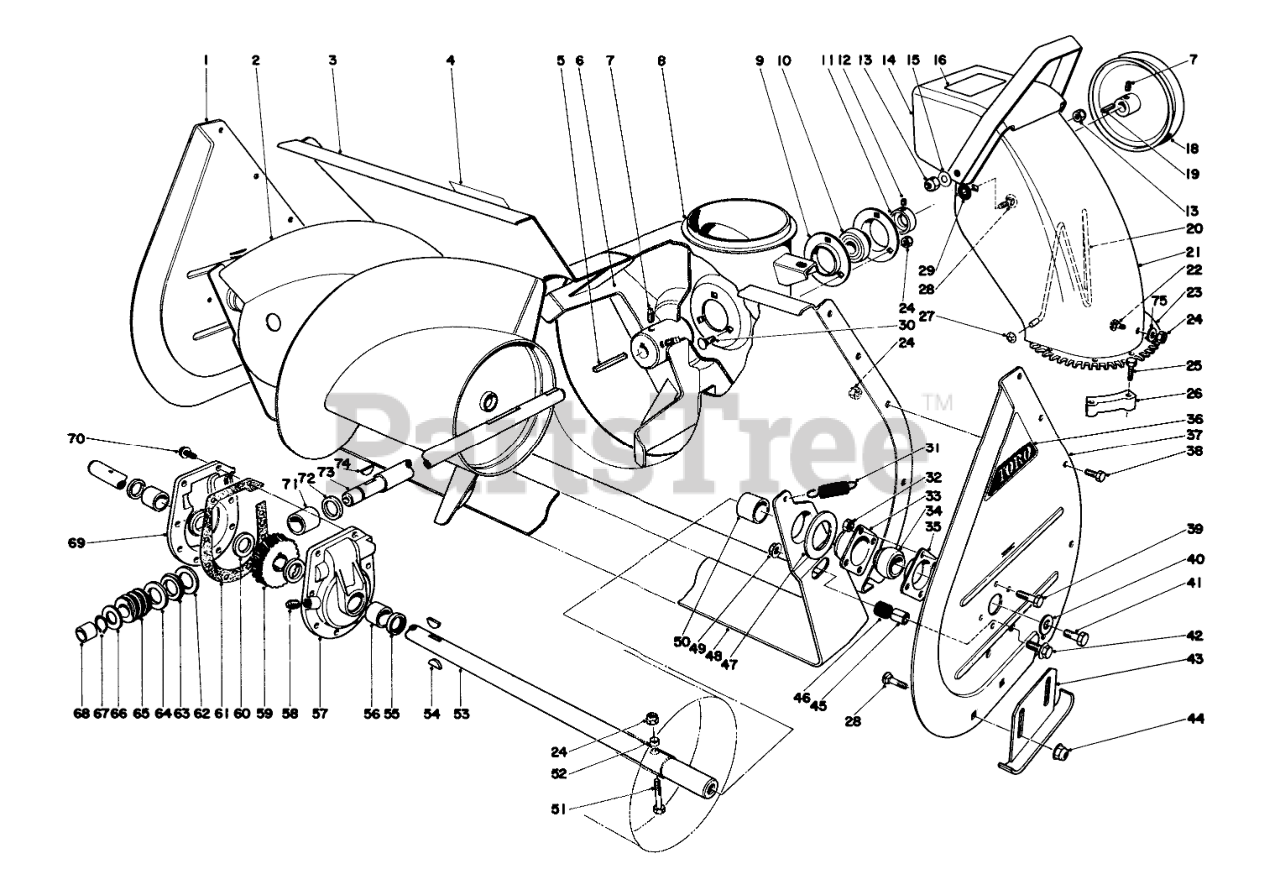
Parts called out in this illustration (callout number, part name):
1	Side Plate
2	Auger R.H.
3	AUGER HSG WA 26" R
4	Decal
6	IMPELLER ASM
7	SCREW-SET, SQH
8	CHUTE RING
9	BRG FLANGE
10	BALL BRG W/COLLAR
11	EXT LOCKING COLLAR
12	SCREW-HSH
13	NUT-LOCK, CONE
14	Deflector (Incl. Ref. #16)
15	WASHER-BELLEVILLE
16	CHUTE WARNING DECAL
18	1/2 X 9.5 DIA PULLEY
19	SQUARE KEY
20	WIRE-CHUTE
21	Upper Chute
22	SCREW-CARR
23	Screw
24	NUT-LOCK, CONE
25	SCREW-TAP
26	RETAINER-CHUTE
27	NUT-PUSH
28	SCREW-CARR
29	WASHER-RUBBER
30	BOLT-CARR
31	SPRING-TENSION
33	BEARING-FLANGE, FRONT
34	BEARING
35	BEARING-FLANGE, REAR
36	AUGER SIDE PLT DECAL
37	Side Plate L. H.
38	SCREW-HH
39	SCREW-HH
40	WASHER
41	SCREW-HH
42	SCREW-HHF
43	Skid
44	NUT-HHF, WHIZ
45	SCRAPER STOP SPACER
46	SCRAPER STOP CUSHION
47	SCRAPER BLADE SPACER
48	SCRAPER BLADE 26 R
49	NUT-HF
50	SPACER
51	Auger Bolt
52	SPACER-HUB, AUGER
53	26 AUGER SHAFT
54	KEY-WOODRUFF
55	SEAL-OIL
56	BUSHING
57	Gear Case L.H. (Incl.Ref. #55-56)
58	PLUG-PIPE, SQH
59	GEAR-WORM, 27T
60	WASHER-THRUST
61	Gasket
62	WASHER-THRUST
63	BEARING-THRUST
64	THRUST-WASHER
66	WASHER-THRUST
67	Ring-Snap
68	BUSHING
69	Gear Case R.H.(Incl. Ref. #55-56)
70	Screw-Self Tapping
71	BUSHING-SPECIAL
72	RING-QUAD
73	SHAFT-IMPELLER
74	KEY-WOODRUFF
75	WASHER-PLAIN
